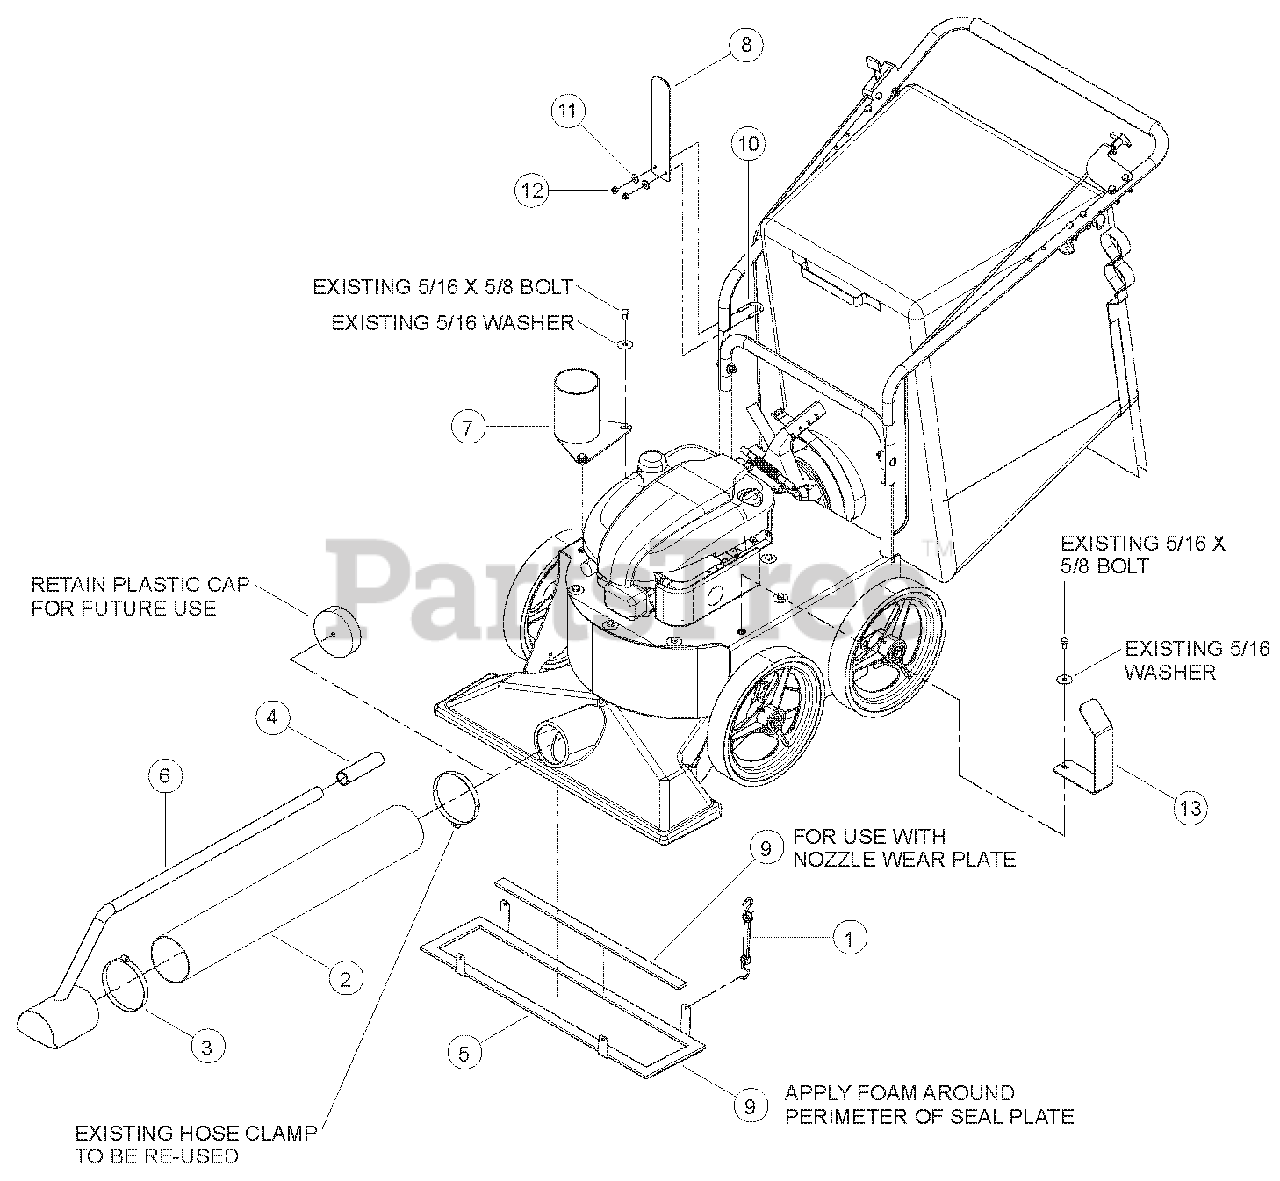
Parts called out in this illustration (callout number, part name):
1	STRAP, 6" TARP
2	HOSE, PVC 4" ID X 10' LG
3	CLAMP, 4" HOSE
4	GRIP - 1" I.D. X 4.63"
5	PLATE, BEAR VAC HOSE KIT SEAL
6	WELDMENT, 4" HOSE NOZZLE
7	WELDMENT, HOSE HOLDER/PLUG
8	STRIP, HOSE HANGER
9	FOAM, PLATE SEAL
10	U-BOLT, 1/4" X 1.0" X 1.75" ZP
11	WASHER, 1/4" FLAT ZP
12	LOCKNUT, 1/4" - 20 NYLON TYPE NE ZP
13	BRACKET, HOSE HOLDER
